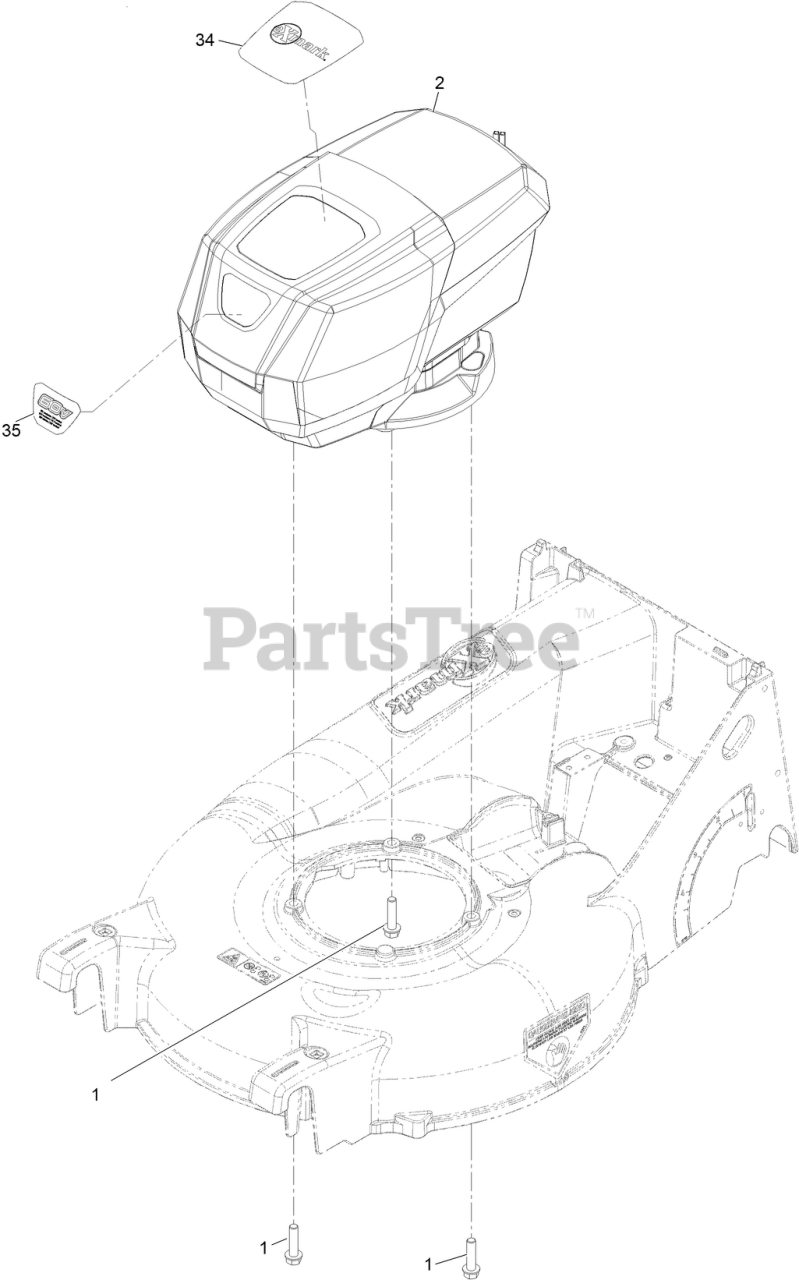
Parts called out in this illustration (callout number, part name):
1	SCREW-HWH
2	MOTOR MODULE
34	DECAL-HOOD,TOP
35	DECAL-HOOD,FRONT
